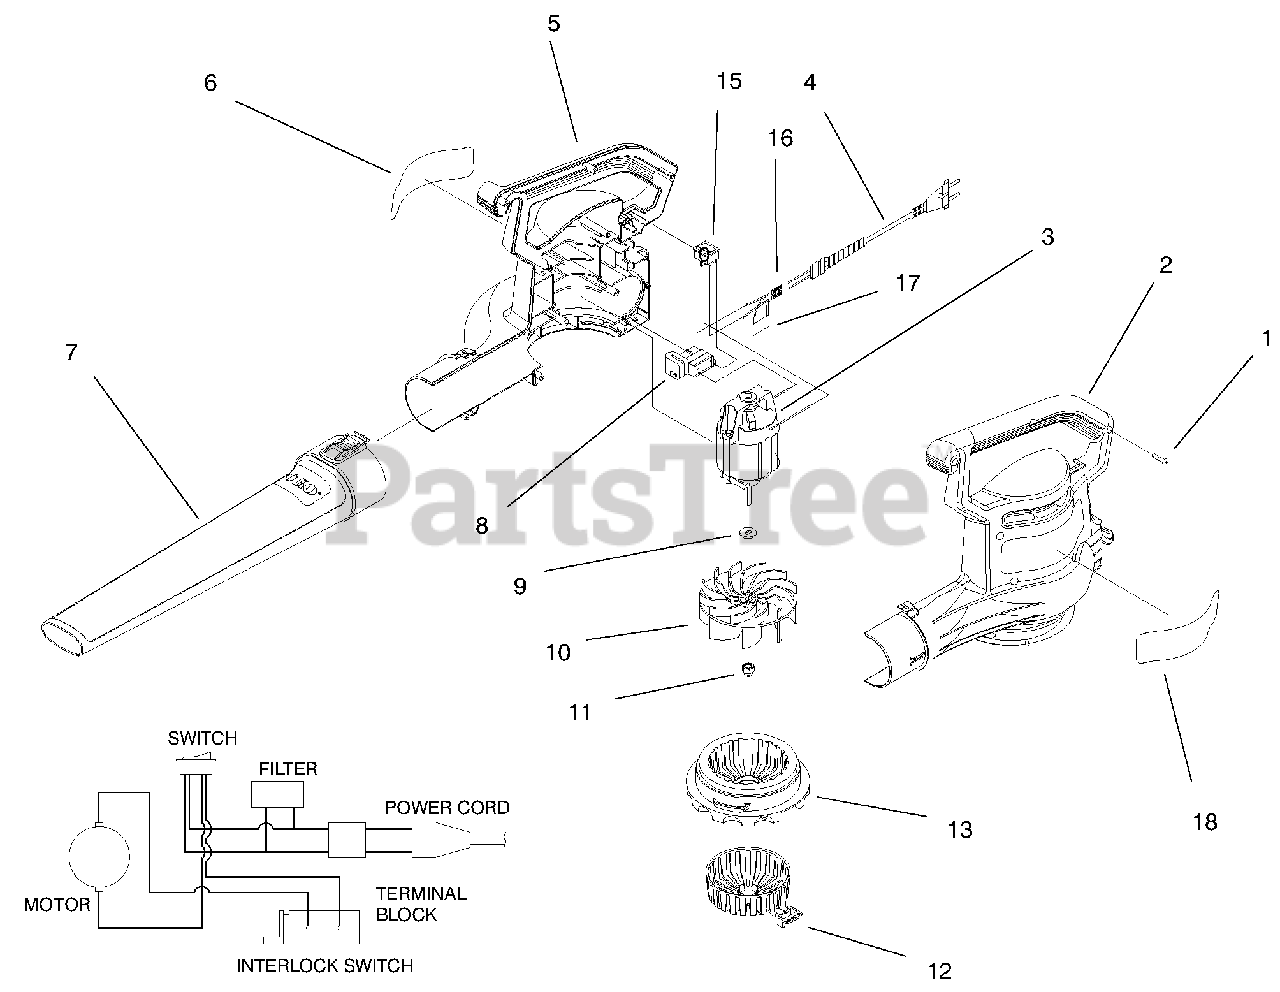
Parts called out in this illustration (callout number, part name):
1	Screw-PH Tap
2	Housing-LH
4	Cord-Supply
5	Housing-RH
6	Decal-Logo
7	Tube-Blower
8	Switch-Interlock
10	Impeller
11	Nut-Impeller
12	Choke-Air
13	Cover-Inlet
15	Switch-Power
16	Terminal Block
17	Filter-RFI
18	Decal-Warning
